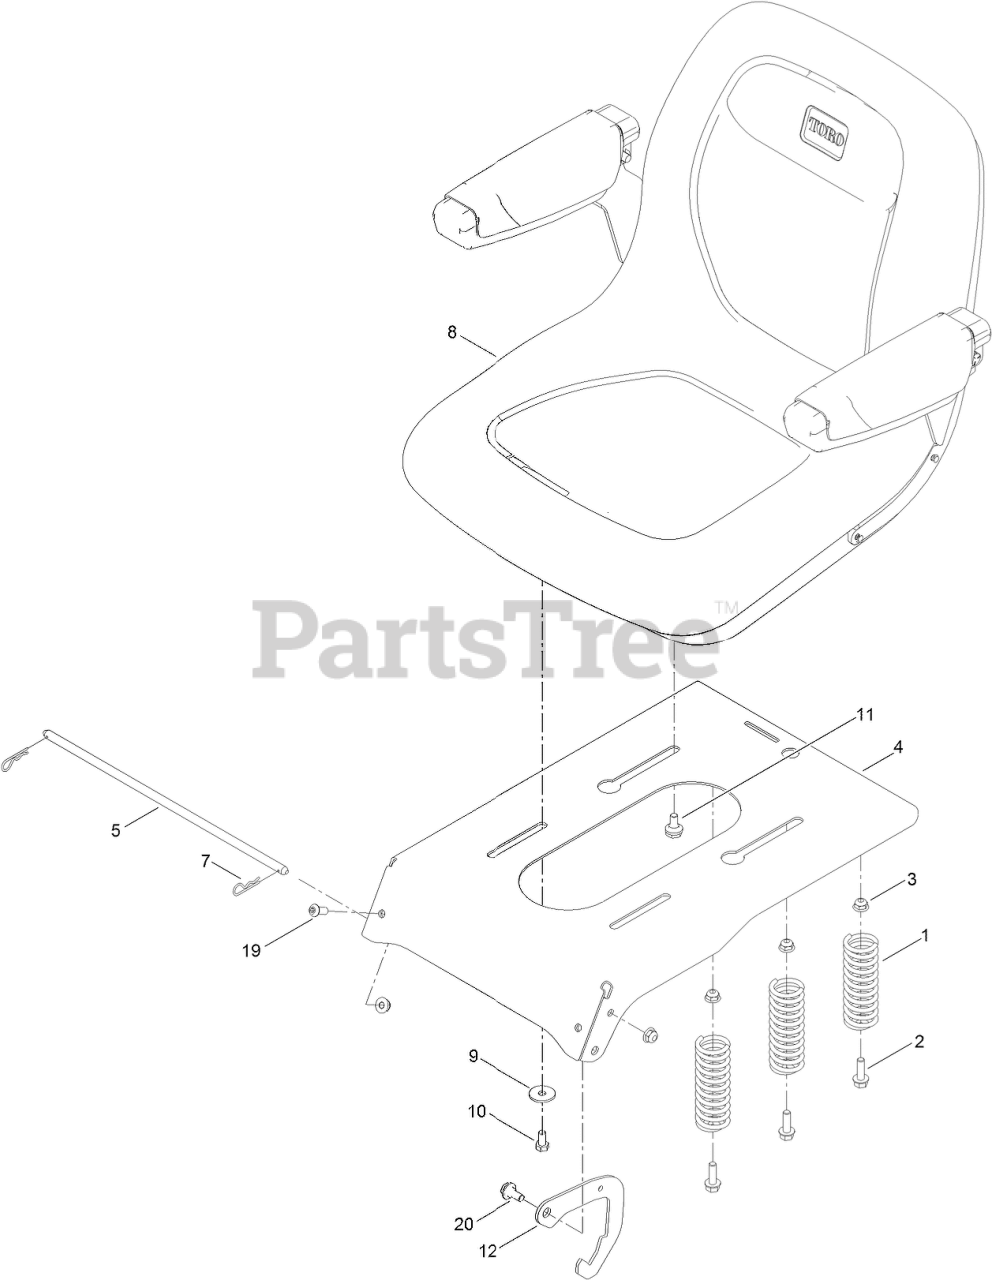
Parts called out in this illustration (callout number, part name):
1	SPRING-COMPRESSION
2	SCREW-HHF
3	NUT-HF
4	PAN-SEAT
5	ROD-PIVOT, NARROW
7	PIN-COTTER
8	SEAT-18 INCH
9	WASHER-PIVOT
10	SCREW-HH
11	BOLT-SHOULDER,HFH
12	SEAT LATCH
19	SCREW-HSBH
20	SCREW-SHOULDER
